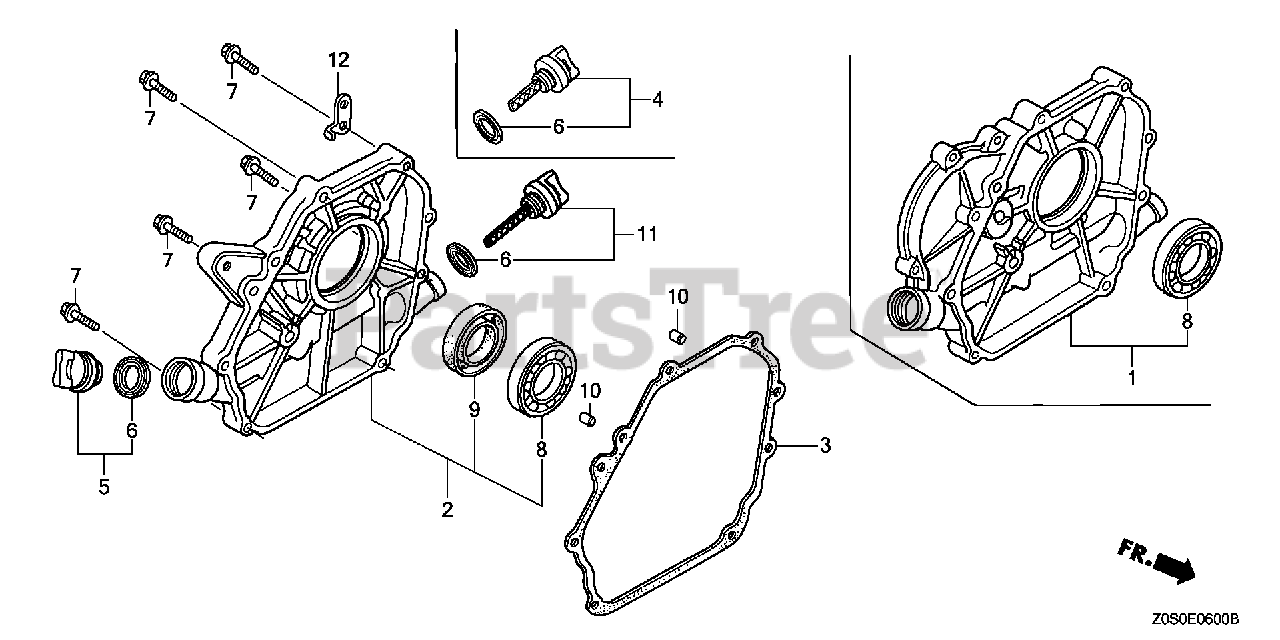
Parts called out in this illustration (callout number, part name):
2	COVER ASSY., CRANKCASE
3	GASKET, CASE COVER
5	CAP ASSY., OIL FILLER (BLACK)
6	GASKET, OIL FILLER CAP
7	BOLT, FLANGE (6X28) (CT200)
8	BEARING, RADIAL BALL
9	OIL SEAL (22X41X6)
10	PIN, DOWEL (8X14)
11	CAP ASSY., OIL FILLER (GAUGE)(GRAY)
